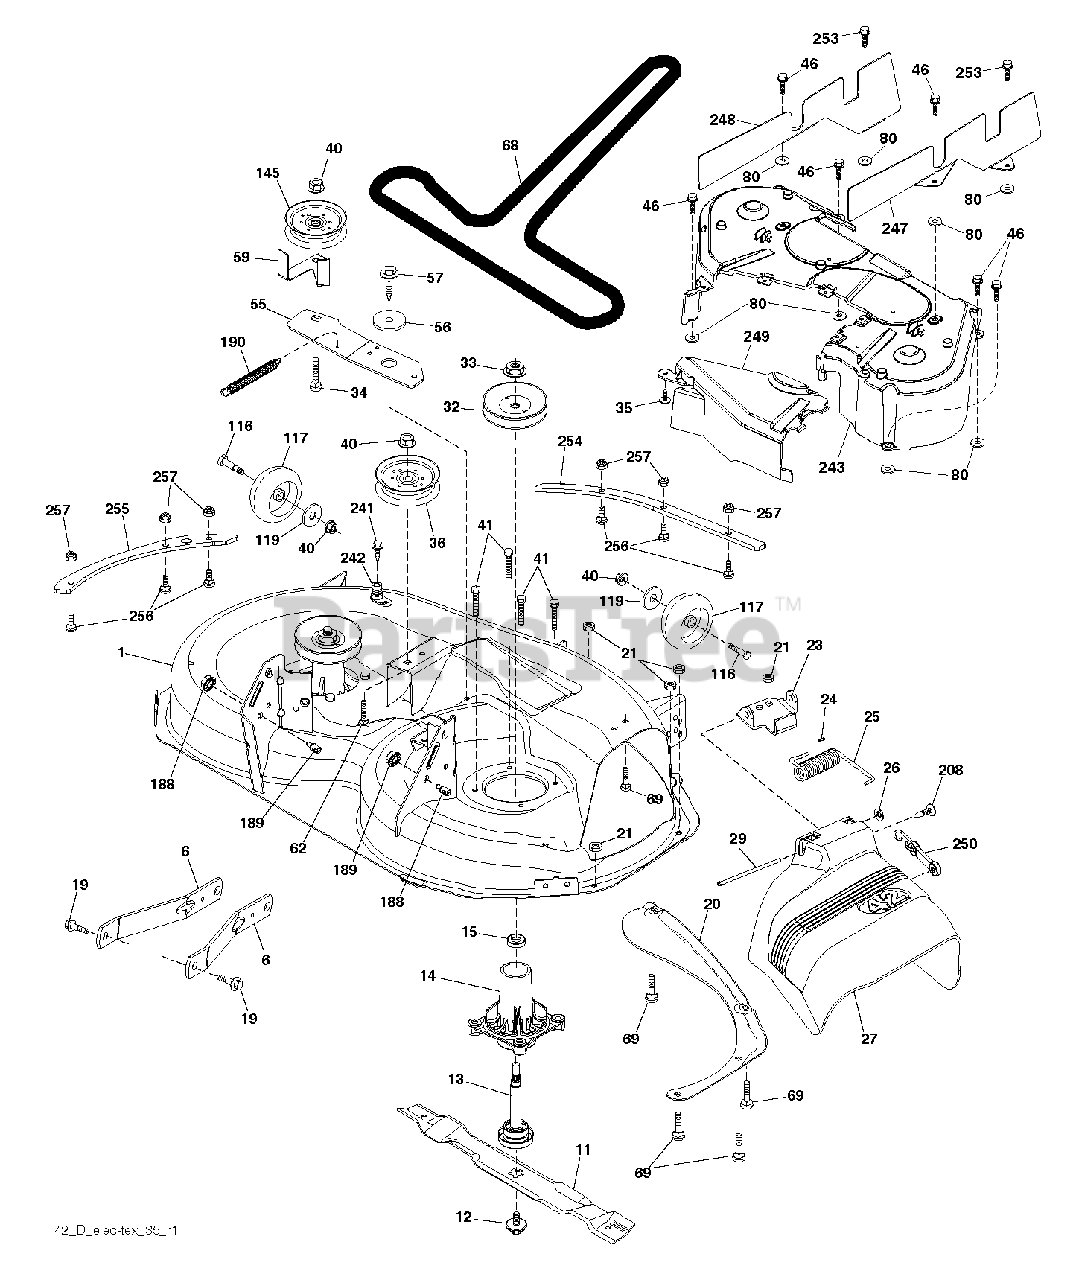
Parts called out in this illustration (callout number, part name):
1	DECK.WELDMNT.42"GREYMS498
6	ARM.SUSPENSION.MOWER.R
11	42" HI-LIFT BLADE
12	SCREW.SEMS.7/16-20X1.HEX.HEAD
13	SHAFT ASM.MNDRL.N/GREASEABLE
14	HOUSING.MANDREL.REV.TALL.N/GRS
15	BEARING.MANDREL.TOP.EXTENDED
19	BOLT.SHOULDER
20	BAFFLE.VORTEX
21	LOCKNUT
23	BRKT.DEFLECTOR.38"2005+
24	CAP-SLEEVE LT
25	SPRING.TORSION.DEFLECT
26	NUT PUSH M
27	DEFLECTOR ASM.42"TEX.FRENCH
29	ROD.HINGE
32	PULLEY/MANDREL
33	NUT.FLANGE.LOCK.TOP
34	BOLT.3/8-16X1.50
35	FASTENER.XMAS.TREE
36	PULLEY.IDLER.2006
40	NUT LOCK FLG 3/8-16 UNC
41	BOLT.HEX.WASHR.HED.313-18X1.19
46	SCREW.1/4-20X5/8
55	IDLER.ARM.42"
56	SPACER.RETAINER
57	SCREW 3/8-16X1
59	GUARD, BELT
68	BELT V SECONDARY
69	BOLT
80	PALNUT 1/4
116	BOLT M
117	WHEEL.GAGE.HALF.SPOKED
119	WASHER
145	PULLEY.IDLER.48"PRIMARY
188	STUD.FASTNER.W/ANTI-ROTATE
189	NUT LOCK HEX FLANGE 5/16-18
190	SPRING.MOWER.DRIVE.ELECTRIC
208	SCREW 3/8-16X1/2
241	SCREW.TT.#10-32X.5.3/8.FLANGE
242	PORT.WASHOUT
243	COVER DECK
247	SHIELD DECK RIGHT
248	SHIELD DECK LEFT
249	COVER CABLE CLUTCH
250	ELASTIC STRAP KIT
253	SCREW
254	PLATES.RENFRC.42DECK.PT431FRNT
255	PLATES.RENFRCE.42DECK.X431SIDE
256	RHSNB, 1/4-20 X 1, GR5
257	NUT T
